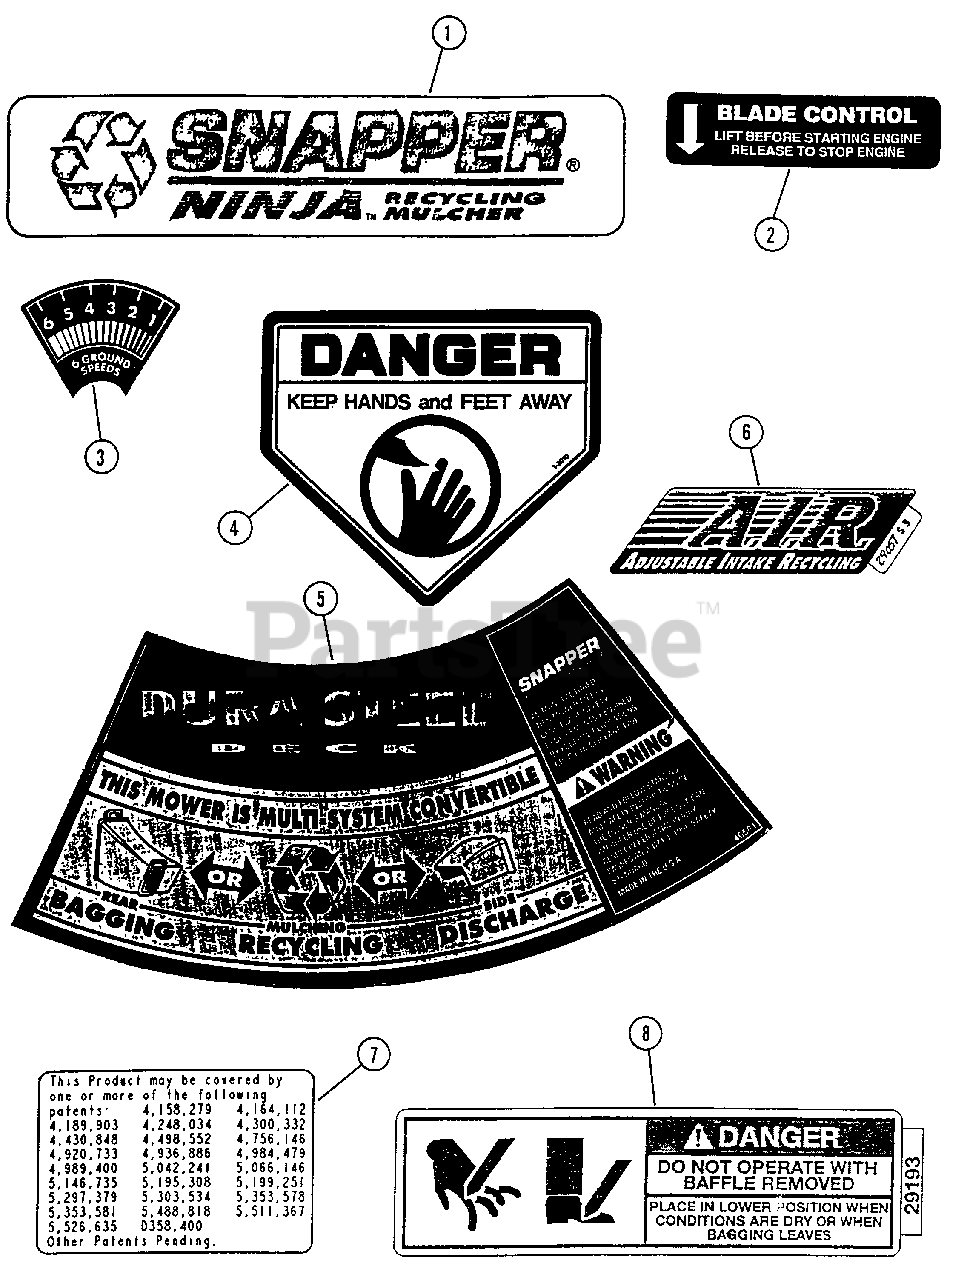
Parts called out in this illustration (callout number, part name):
1	LOGO, Recycling Mulcher (Ninja)
2	DECAL, Blade Control
3	DECAL, Speed Sector
4	DECAL, Danger
5	DECAL, Convertible
6	DECAL, Medallion- Deck
7	DECAL, Patent Numbers
8	DECAL, Front Baffle
